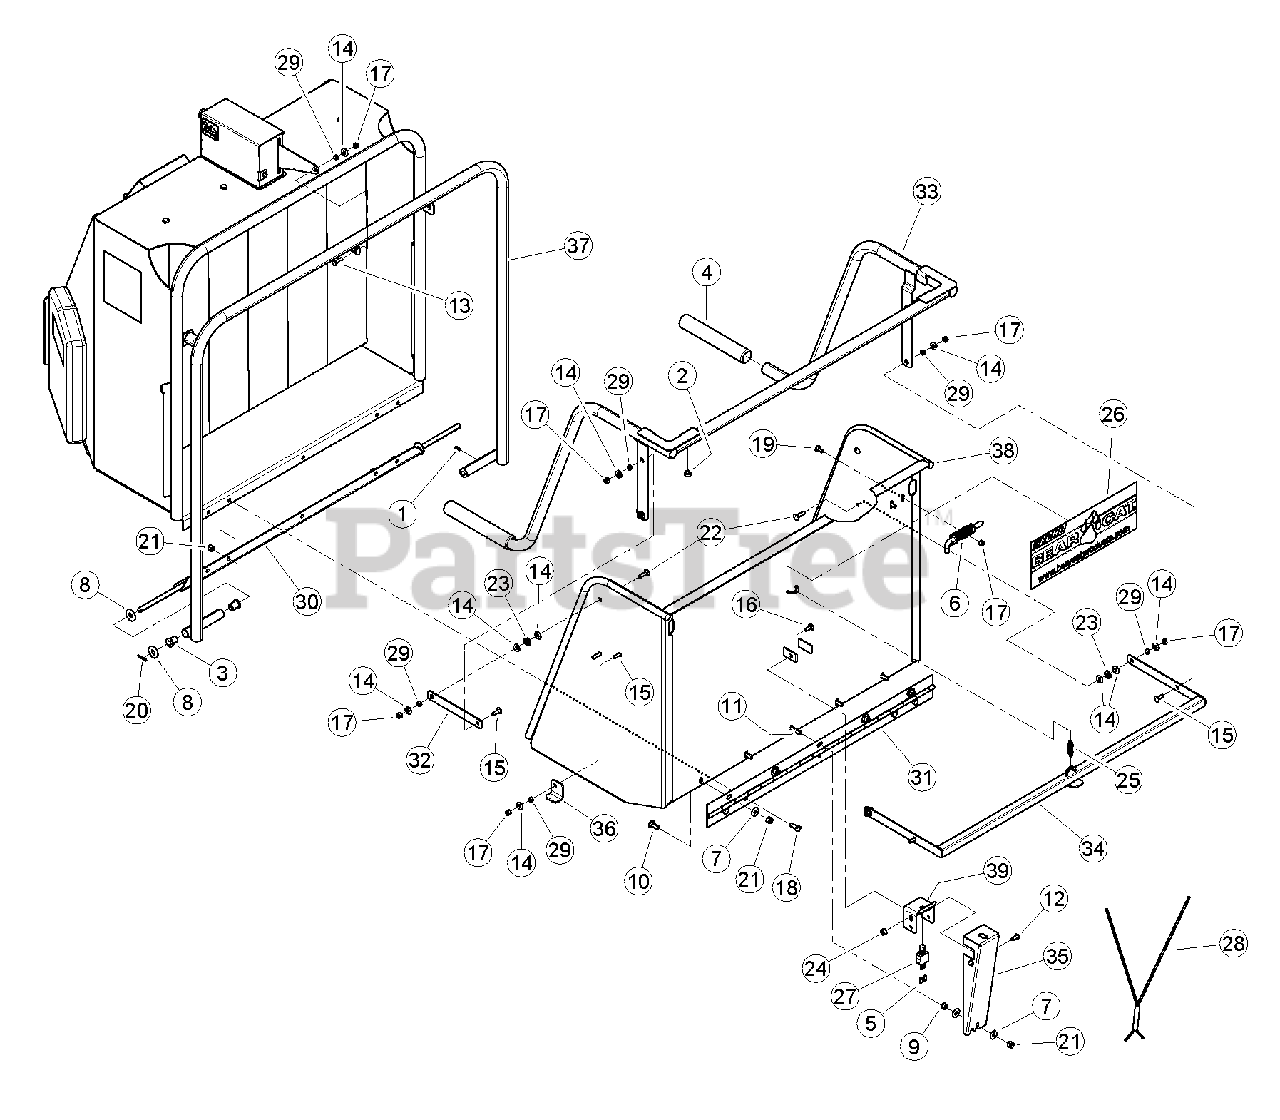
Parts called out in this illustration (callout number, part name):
1	FITTING, 1/4 SELF-TAP GREASE
2	BUMPER, RUBBER
3	BUSHING, 1/2 X 1 FLANGE LUBE
4	GRIP, 1.219 X 10.00
5	CONNECTOR, 1/4 QD MALE
6	LATCH, RH HINGE
7	WASHER, 3/8 FLAT ZP
8	WASHER, 1/2 FLAT ZP
9	NUT, 3/8 SERR FLANGE NC ZP
10	BOLT, 3/8 X 1 CRG GR5 NC ZP
11	BOLT, 3/8 X 1-1/2 CRG GR5 NC ZP
12	SCREW, 11/32 X 7/8 HWH AB THREAD ZP
13	BOLT, 5/16 X 1 HEX HD GR5 NC ZP
14	WASHER, 5/16 FLAT ZP
15	BOLT, 5/16 X 1 CRG GR5 ZP
16	BOLT, 5/16 X 7/8 CRG GR5 NC ZP
17	NUT, 5/16 NE NYLOCK ZP
18	BOLT, 3/8 X 1-1/4 HEX HD GR5 ZP
19	BOLT, 5/16 X 3/4 CRG GR5 NC ZP
20	PIN, 1/8 X 1.00 COTTER ZP
21	NUT, 3/8 NE NYLOCK ZP
22	BOLT, 5/16 X 1-1/4 CRG GR5 ZP
23	WASHER, 5/16" ID 7/8" OD NYLON FLAT
24	NUT, 5/16-18 NYLOCK-FLANGE
25	SPRING 1/2 X 2.00 LG,ZP
26	DECAL, BEARCAT WEB
27	SWITCH, MOMENTARY IP67 NORMALLY ON
28	HARNESS, SAFETY BAR
29	SPACER, IDLER PIVOT
30	WELDMENT, CONTROL PIVOT
31	HINGE, EXTENSION TRAY
32	LINK, PARALLEL
33	WELDMENT, KNEEBAR
34	WELDMENT, KNEEBAR PIVOT
35	SHIELD, KNEEBAR SWITCH
36	LOCK, SAFETY BAR
37	WELDMENT, CONTROL ARM
38	WELDMENT, EXTENSION TRAY
39	BRACKET, SWITCH
